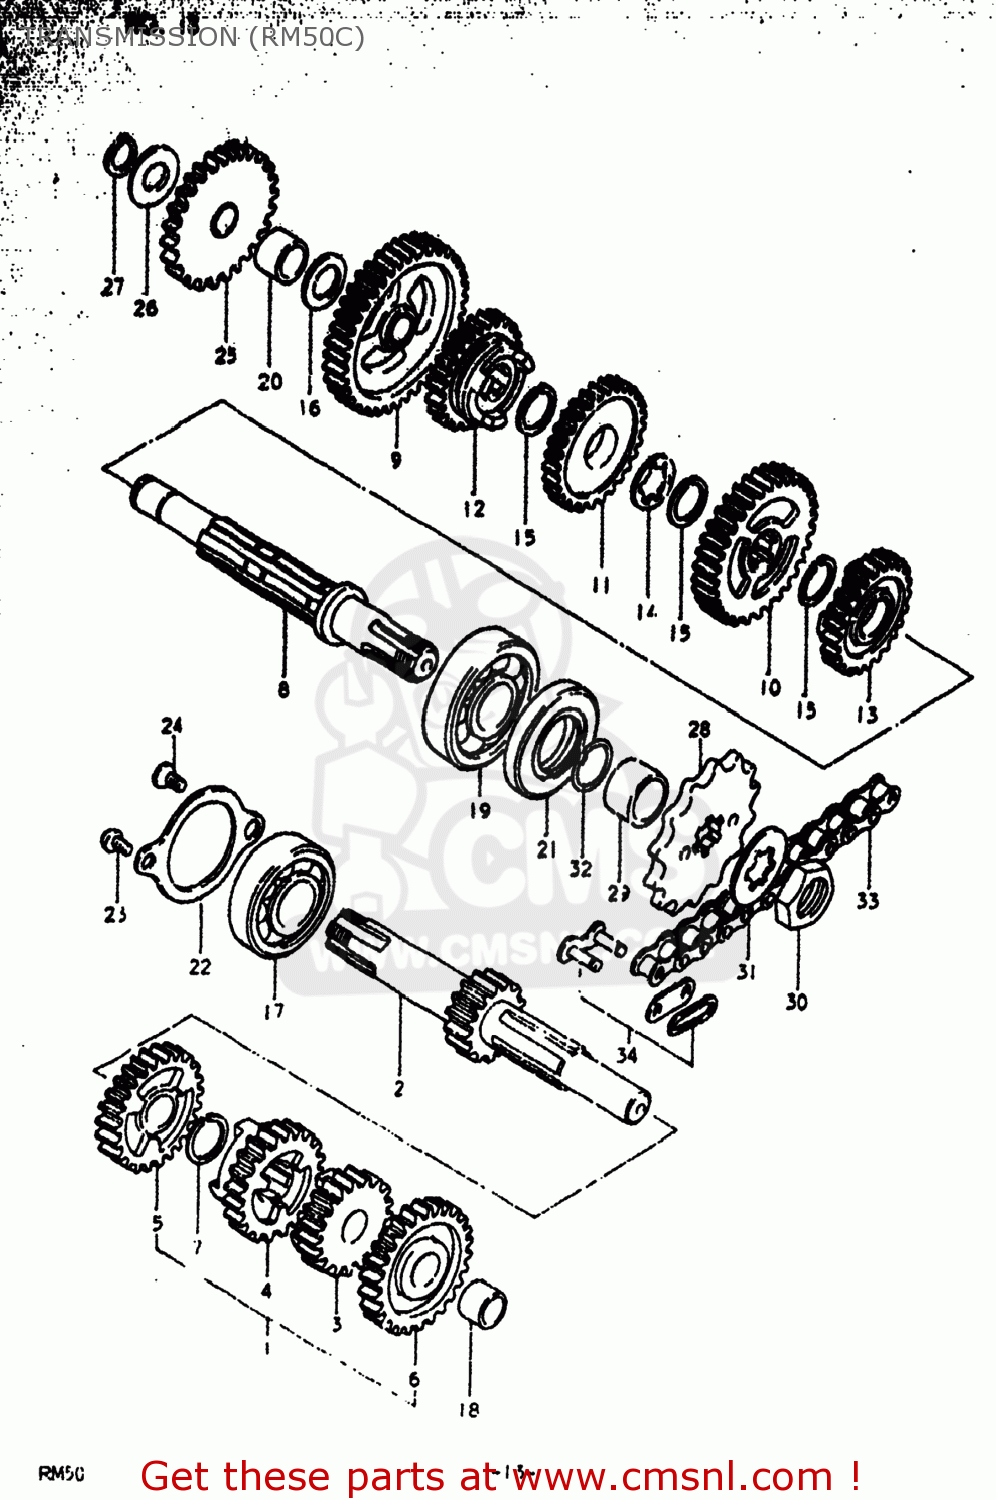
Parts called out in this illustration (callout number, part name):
1	SHAFT,COUNTER
2	SHAFT,COUNTER(NT:12)
3	GEAR,SECOND DRIVE
4	GEAR,THIRD DRIVE
5	GEAR,4TH DRIVE(NT:24)
6	GEAR,FIFTH DRIVE
7	CIRCLIP
8	SHAFT,DRIVE
9	GEAR,FIRST DRIVEN
10	GEAR,2ND DRIVEN(NT:33)
11	GEAR,3RD DRIVEN(NT:29)
12	GEAR,FOURTH DRIVEN
13	GEAR,5TH DRIVEN(NT:24)
14	WASHER(13X24X1)
15	CIRCLIP
16	WASHER,LOCK
17	BEARING
18	BUSH
19	BEARING
20	BUSH
21	SEAL,OIL(21X40X6)
22	RETAINER,CNTR SHAFT BEARING
23	SCREW
24	SCREW
25	GEAR,KICK STARTER IDLE
26	WASHER
27	CIRCLIP
28	SPROCKET,ENGINE
29	SPACER(17X21X13)
30	NUT
31	WASHER
32	O RING(D:1,ID:16.8)
33	CHAIN ASSEMBLY,DRIVE
34	JOINT ASSEMBLY,CHAIN
